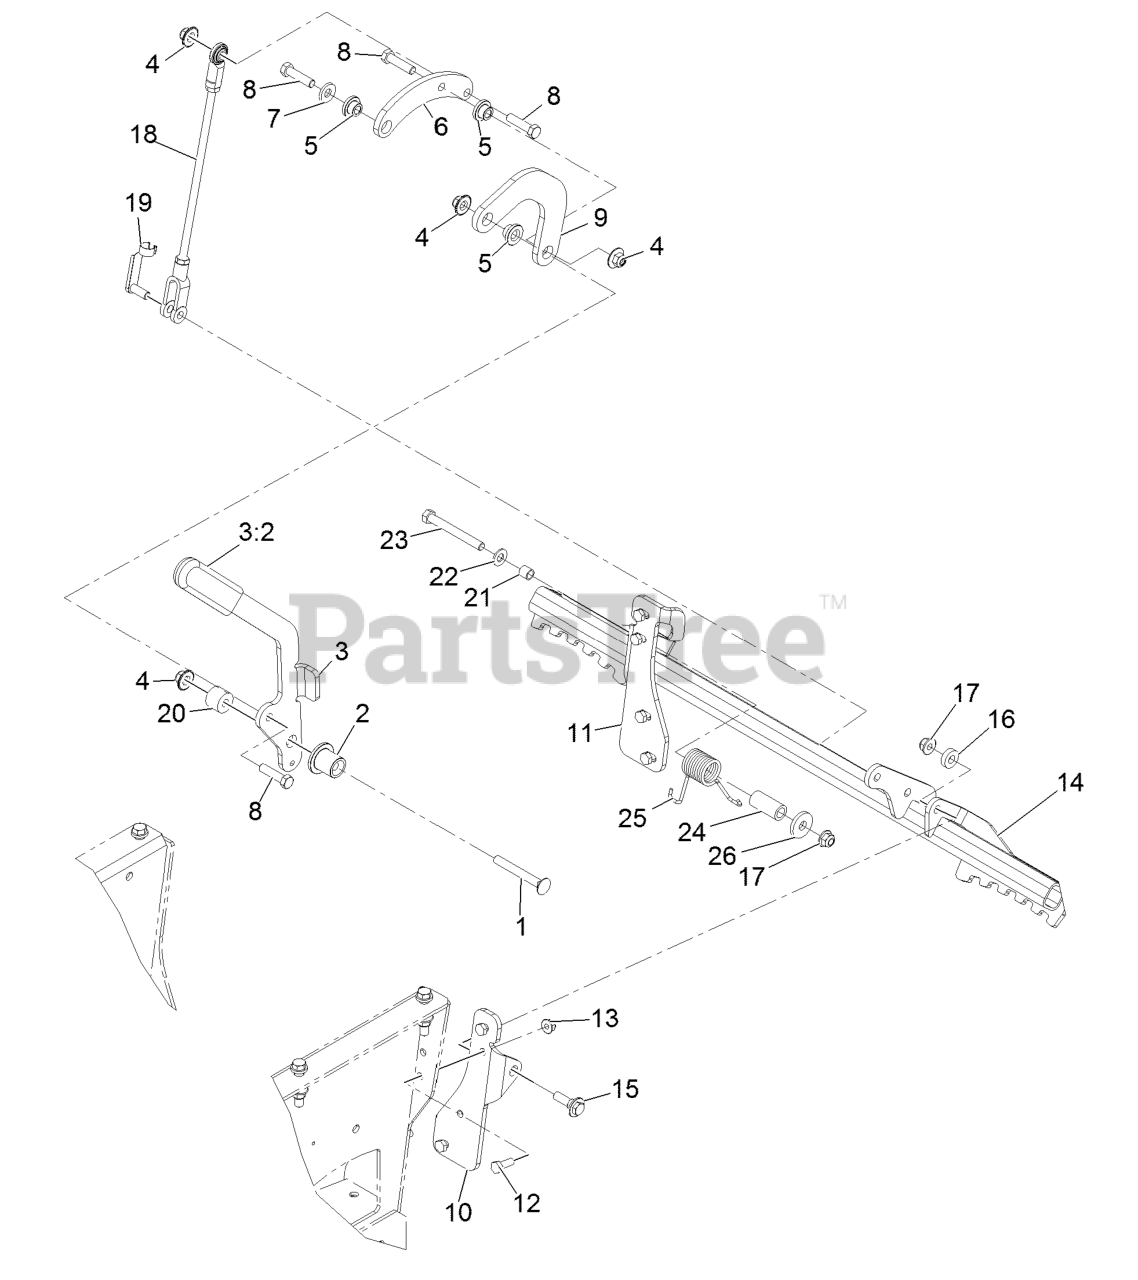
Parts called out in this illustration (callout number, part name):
1	Bolt-Carriage 3/8-16 X 3
2	Bushing-Handle
3	Handle-W/Grip ASM
3:2	Grip-Lever
4	Nut-Nyloc 3/8-16 Flg
5	Bushing-Flanged
6	Arm-Brake Bellcrank
7	Washer-Spring Disc 3/8
8	Screw-HH 3/8-16 X 1 1/2
9	Link-Brake Handle
10	Bracket-Brake Mount, LH
11	Bracket-Brake Mount, RH
12	Screw-HH 5/16-18 X 7/8
13	Nut-Nyloc 5/16-18 Flg
14	Bar-Brake
15	Screw-Shoulder 3/8-16 X 1.295
16	Spacer
17	Nut-Nyloc 3/8-16 Flg
18	ASM-Brake Linkage
19	Pin-Clevis Spring 3/8
22	Washer-3/8 SAE
23	Screw-HH 3/8-16 X 3-1/4
25	Spring-Torsion
